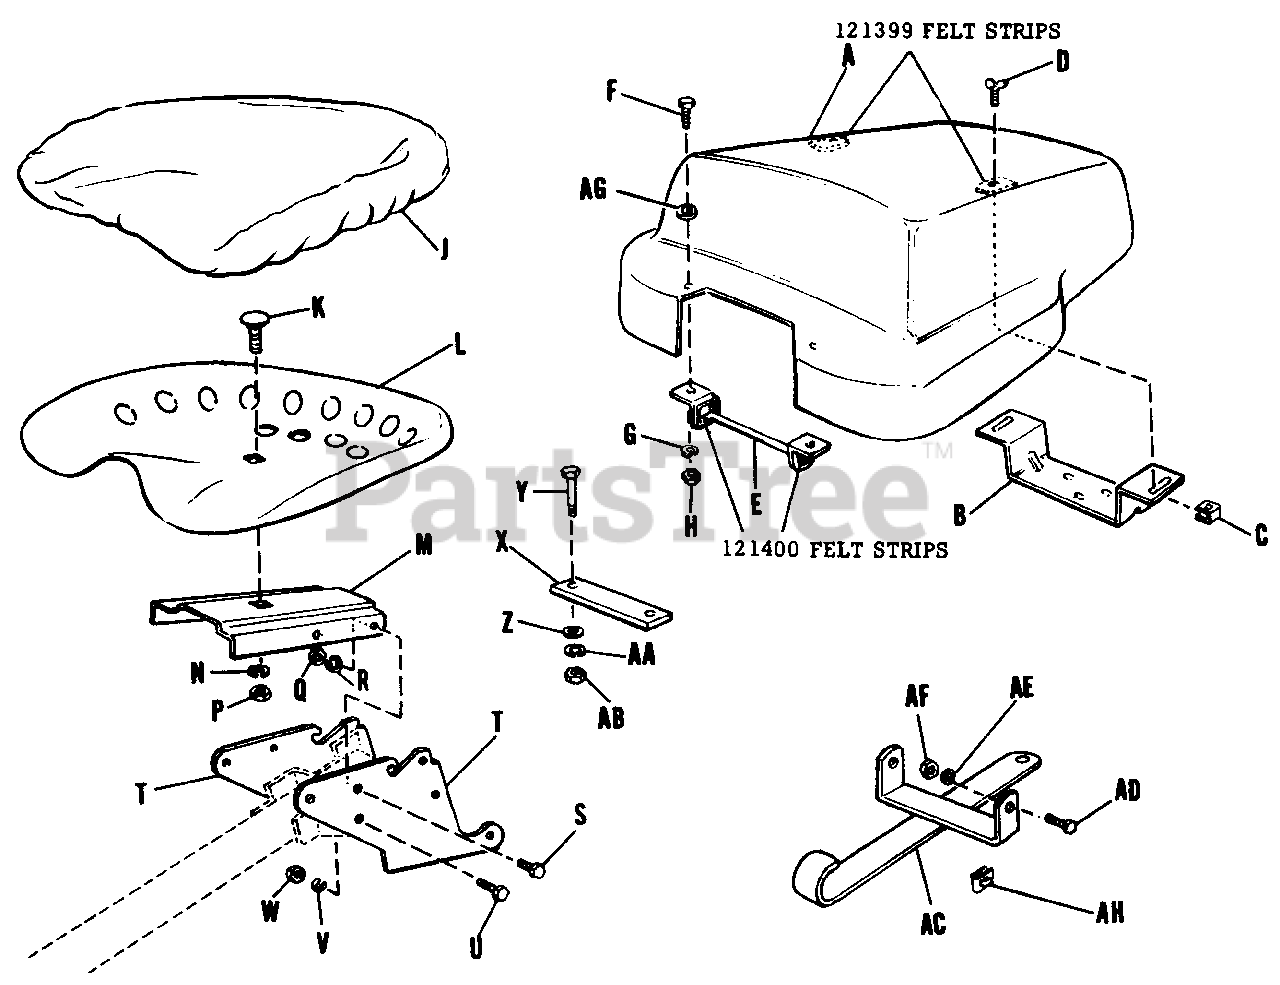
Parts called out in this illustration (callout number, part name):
B	Hood Bracket
C	Nut, Tinnerman
D	Thumb Screw
E	Bracket Assembly, Hood
F	Capscrew, Hex, 1/4-20 x 3/4
G	Washer, Lock, 1/4
H	Nut, Hex, Full, 1/4-20
K	Carriage Bolt, 1/2-13 x 1 lg.
M	Seat Support
N	Washer, Lock, 1/2
P	Nut, Hex, Full 1/2-13
Q	Nut, Hex, Full 3/8-16
R	Washer, Lock, 3/8
S	Capscrew, Hex, 3/8-16 x 1 lg.
T	Side Plate
U	Capscrew, Hex Hd., 3/8-16 x 1 lg.
V	Washer, Lock, 3/8-16
W	Nut, Hex Full, 3/8-16
X	Spacer, Engine
Y	Capscrew, Hex, 5/16-18 x 2
Z	Washer, Plain, 5/16
AA	Washer, Lock, 5/16
AB	Nut, Hex, Full, 5/16-18
AC	Draw Bar Assembly
AD	Capscrew, Hex, Lock 3/8-16
AE	Washer, Lock, 3/8-16
AF	Nut, Hex, Full, 3/8-16
AG	Washer, Plain, 1/4
